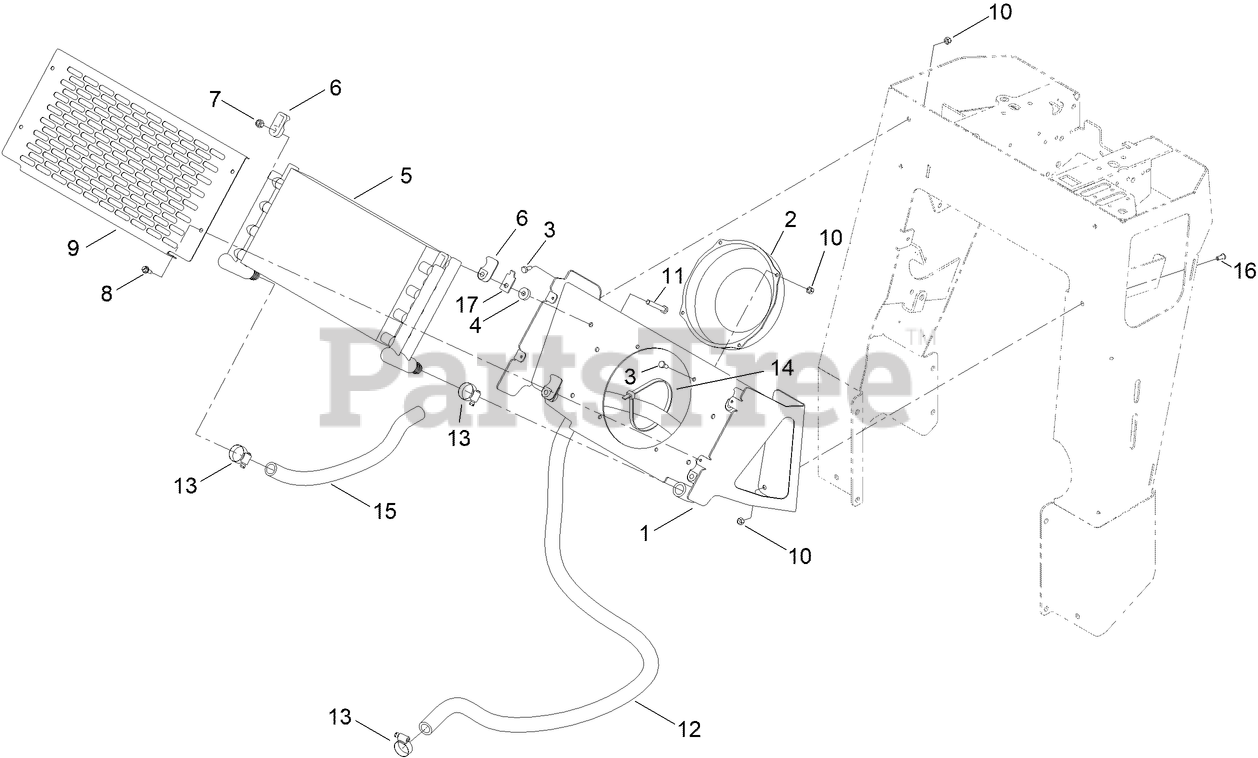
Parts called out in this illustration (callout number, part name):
1	COOLER MOUNT ASM [RED]
3	SCREW-HH
5	COOLER-OIL
7	NUT-LOCK, NI
8	SCREW-HWH
9	COVER-COOLER
10	NUT-LOCK, NI
11	SCREW-HH
12	HOSE-RETURN
13	CLAMP-HOSE
14	TIE-CABLE
15	HOSE-RETURN
16	SCREW-HSBH
17	PLATE-SUPPORT, CLAMP
